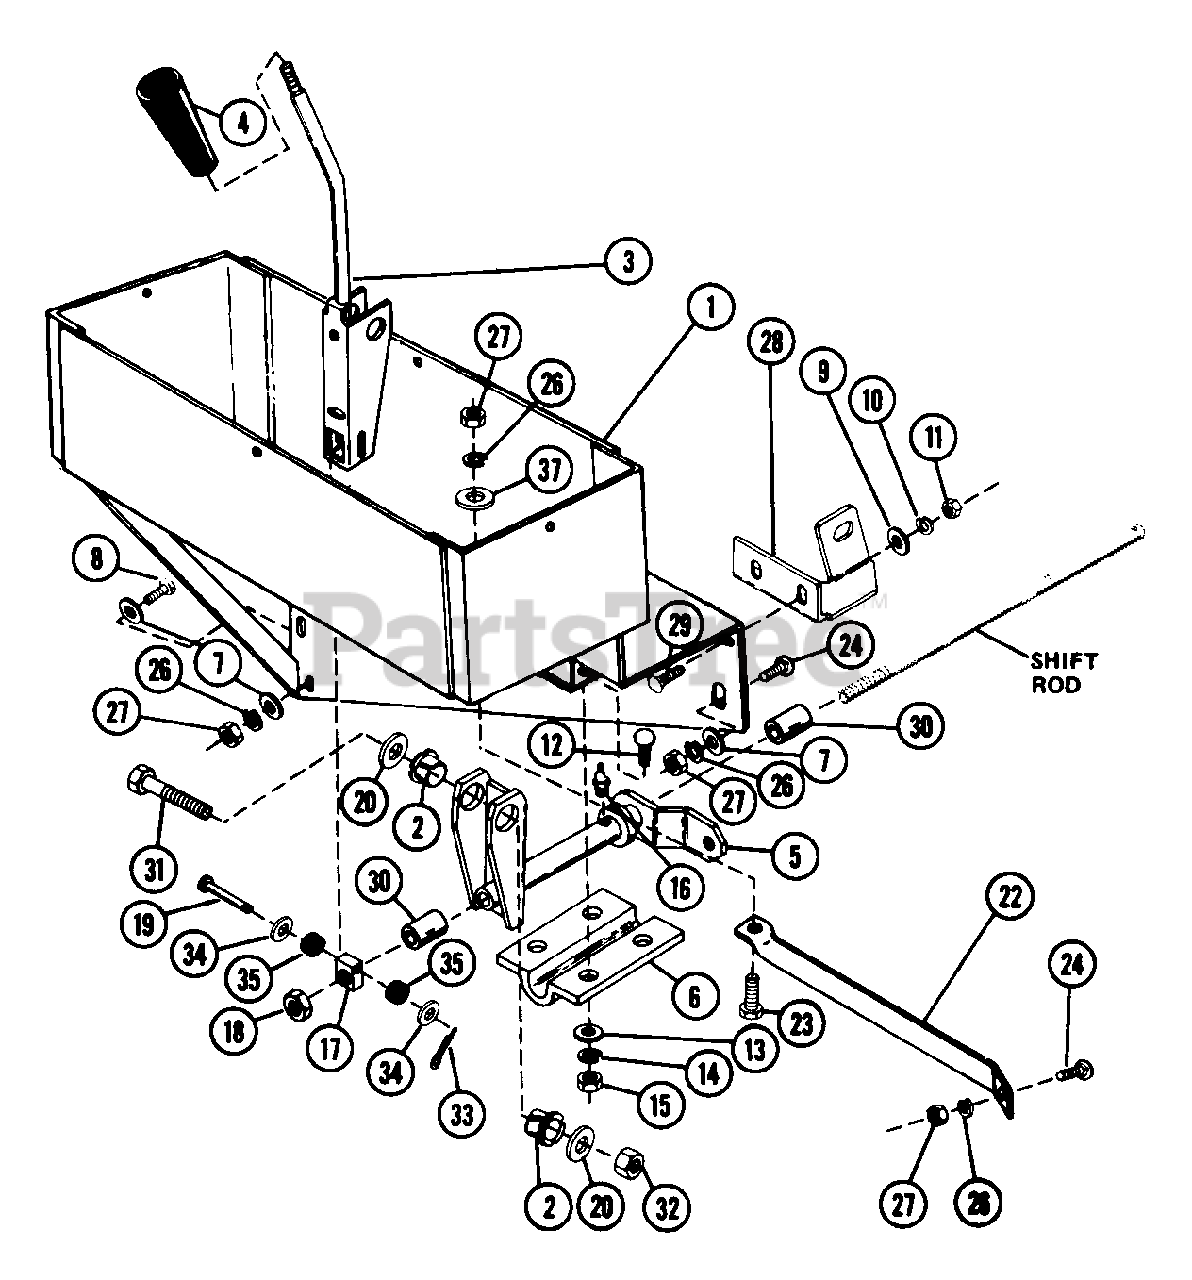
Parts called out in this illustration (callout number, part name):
1	CONTROL BOX
2	BSHG-FL .437X.500X.437X.656
3	SHIFT HANDLE
4	HANDLE
5	SHIFT LEVER ASSEMBLY
6	SHIFT SUPPORT
7	WSHR-FL-STL .438X1.0X.083 PL
8	BLT-HEX .38-16X1.00 PL
9	WSHR-FL-STL .38X.875X.083 PL
10	WSHR-LK .312X.097 PL HVY
11	NUT-HEX .312-18
12	BLT-RDHDSQNK .25-20X.62 PL
13	WSHR-FL-STL.312X.734X.065PL
14	WSHR-LK .250X.077 HVY PL
15	NUT-HEX .250-20 PL
16	SPIN DRIVE ZERK FITTING
17	ADJUSTING BLOCK
18	NUT-LK-CTR .50-13
19	CLEVIS PIN
20	WSHR-FL-STL .469X.937X.065 PL
23	BLT-HEX .38-16X.75 PL GR2
24	BLT-RDHDSQSHNK .38-16X1.00 PL
25	WSHR-FL-STL .438X1.0X.083 PL
26	WSHR-LK .375X.094 MED PL
27	NUT-HEX .375-16
28	SWITCH BRACKET
29	BLT-RDHDSQNK .31-18X.75 GR5 PL
30	BSHG-SLV .500X.687X.500
31	BLT-HEX .44-14X2.75
32	NUT-LK-TOP .437-14 GR C PL
33	PIN-COTR .09X.75 PL
34	WSHR-FL-STL .281X1.250X.048PL
35	GROMMET
37	WSHR-FL-STL.406X.812X.065PL
